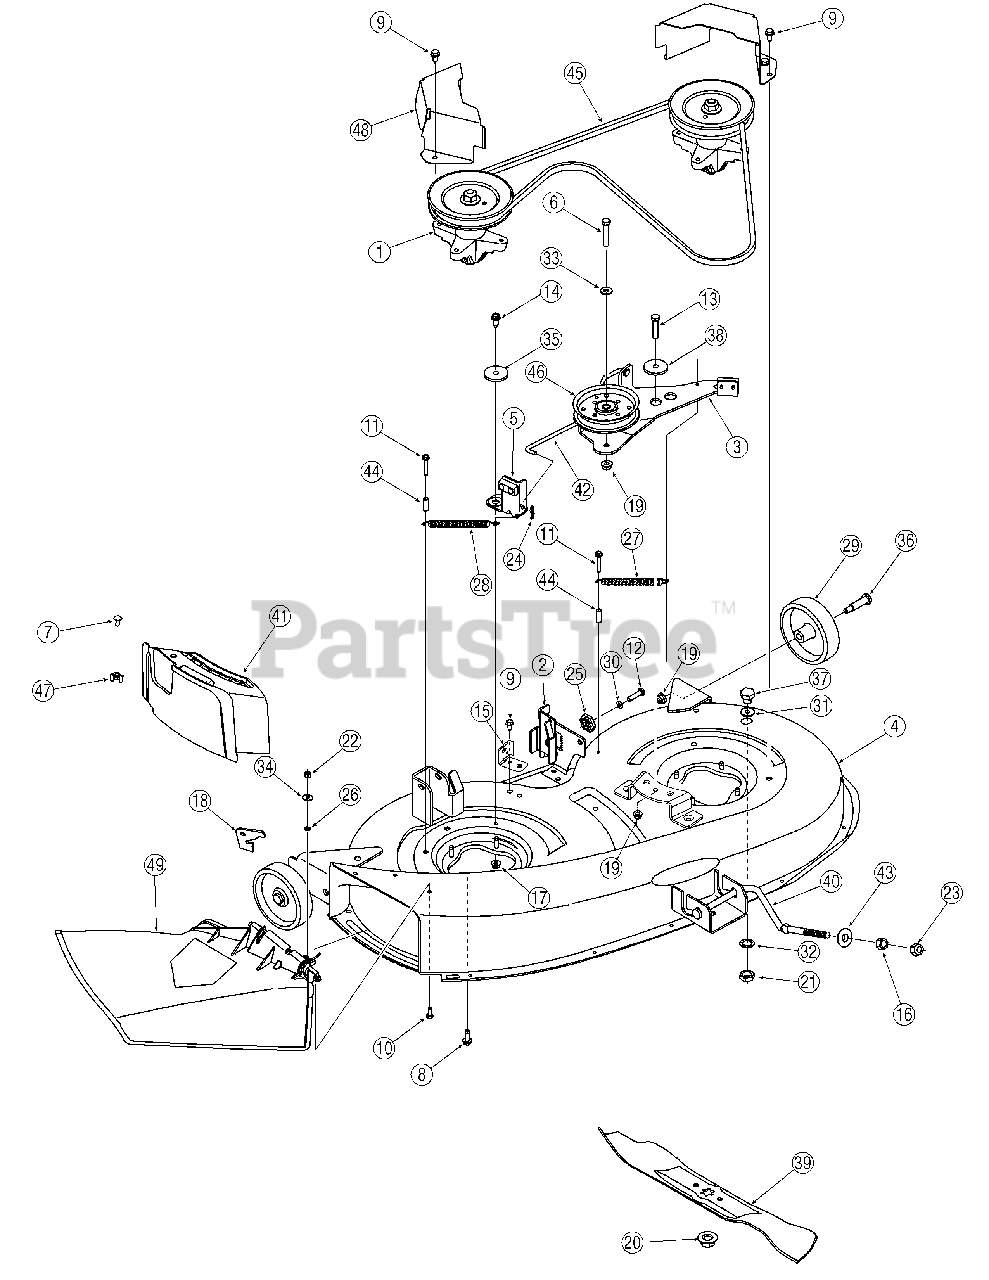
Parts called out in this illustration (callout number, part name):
1	Spindle Assembly, with Pulley, 5.75"
6	Screw, 3/8-16, 1.75, Gr5
7	Carriage Screw, , 1/4-20 x .62 (if equipped)
8	Screw, 5/16-18, 0.875
9	Screw, 5/16-12, 0.750
10	Screw, 1/4-20, .75, Gr5
11	Screw, 1/4-20, 1.500
12	Screw, 5/16-18, 1.250
13	Screw, 3/8-16, 1.25, Gr5
14	Screw, 5/16-18, .75, Gr5
16	Nut, Hex, 1/2-13, Gr5
17	Nut, Flange Lock, 5/16-18, GrF
18	Chute Stop
19	Nut, Flange Lock, 3/8-16, GrF
20	Nut, Flange, 5/8-18
21	Nut, Hex, M16-1.5
22	Nut, Hex, 1/4-20, Gr5
23	Nut, Hex Lock, 1/2-13, Gr8, Nylon
24	Pin, Cot, .072 Dia. x 1.13
25	Gear, Deck Adjustment
26	Nut, Push, .25 ID x .50
27	Spring, Exten. , .75 Dia. X 6.375
28	Spring, Exten. , .50 Dia. X 6.375
29	Wheel, Deck 5.0 x 1.38 (if equipped)
30	Washer, Lock, 5/16
31	Washer, Flat, .64 x 1.24 x .06
32	Washer, Lock, 5/8, Internal
33	Washer, Flat, .385 x .87 x .06
34	Washer, Bell, .265 x.75 x .062
35	Spacer, Shoulder, .5000 x .1475
36	Screw, Shldr, .498 x 1.53, 3/8-16 (if equipped)
37	Plug, Screw, M16 x 1.5
38	Spacer, Shoulder, .8840 x .190
39	Blade, 19.38", Star 3-in-1
40	Deck Rod, Front Adjustable
41	Mulch Plug (if equipped)
42	Control Rod, Brake
43	Pivot Cup, Deck Lift
44	Spacer, .260 x .372 x 1.030
45	Belt, V-Type
46	Idler Pulley, 4.25" Dia.
47	Wing Nut, 1/4-20 (if equipped)
49	Chute Assembly, Discharge
